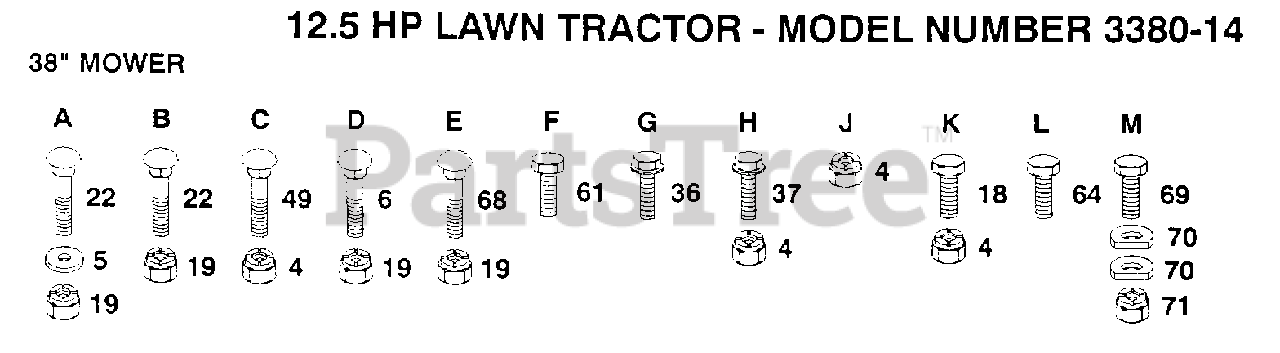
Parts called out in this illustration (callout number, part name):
5	WASHER M
6	BOLT
22	BOLT
36	SCREW
37	SCREW
49	BOLT
61	BOLT
64	BOLT.3/8-14X1.25
69	BOLT LT
70	WASHER T
